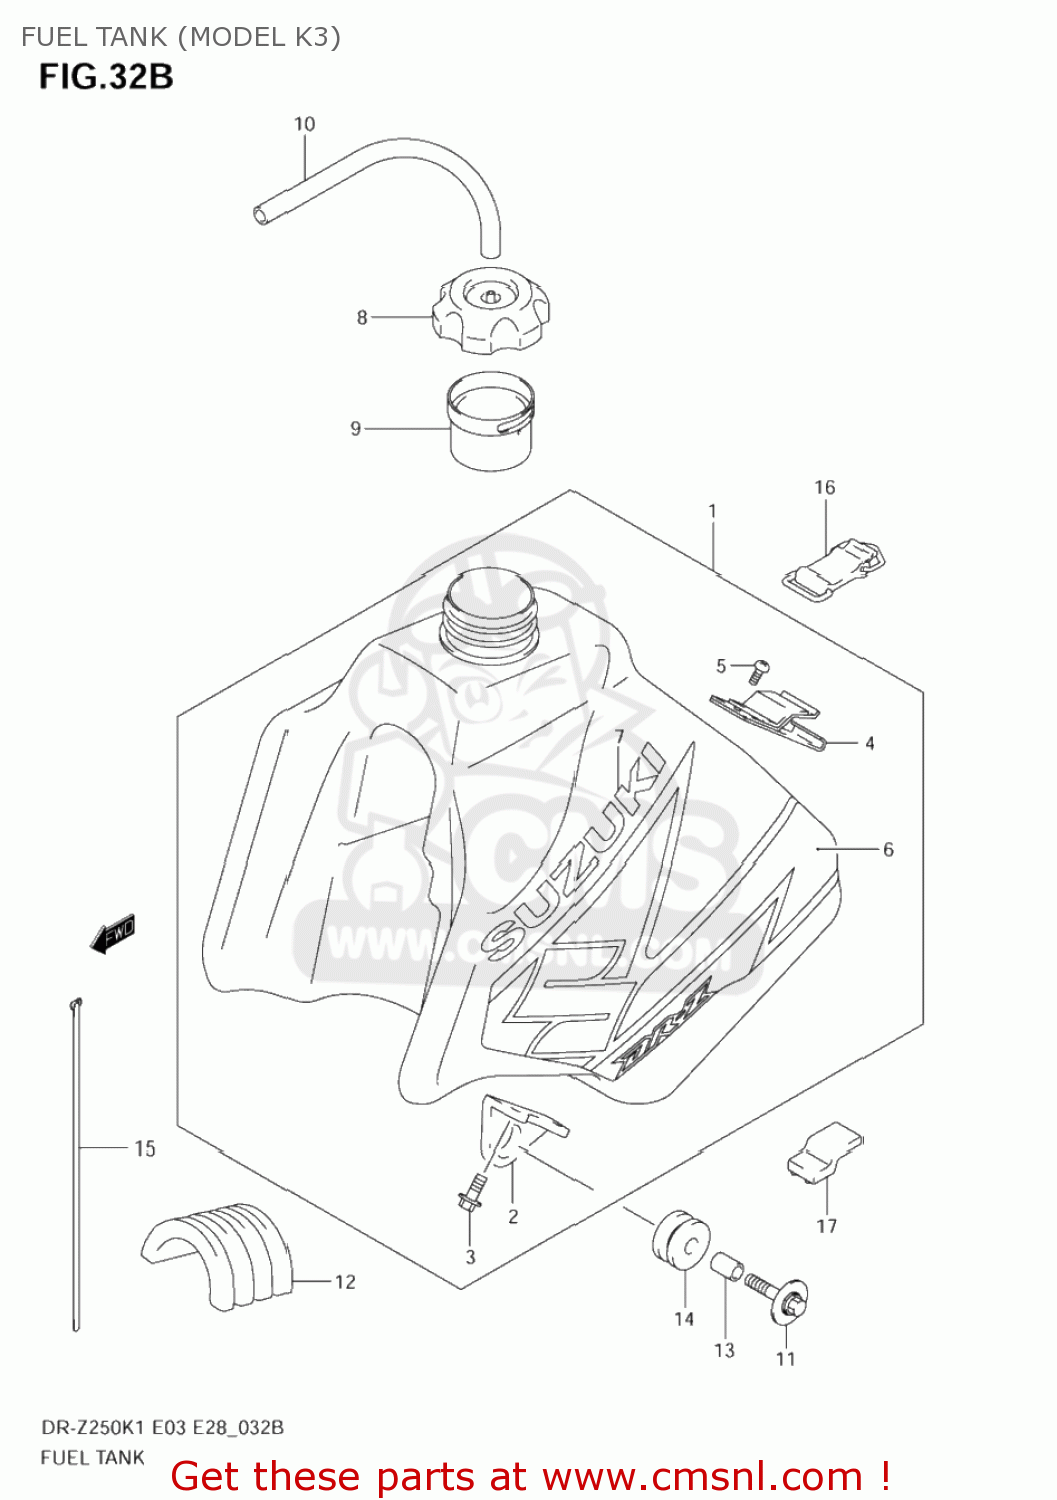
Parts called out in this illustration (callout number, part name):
1	TANK ASSY, FUEL (YELLOW)
2	BRACKET,FUEL TANK FR
3	BOLT
4	BRACKET,FUEL TANK RR
5	SCREW
6	TAPE SET,FUEL TANK
7	EMBLEM
8	CAP ASSY,FUEL TANK FILLER
9	TUBE,FILLER INLET
10	HOSE(5X8.2X600)
11	BOLT(6X30)
12	CUSHION,FUEL TANK
13	SPACER(6.5X9X13.5)
14	CUSHION,MUFFLER
15	CLAMP(L:300)
16	BAND,FUEL TANK RR
17	CUSHION,FUEL TANK
